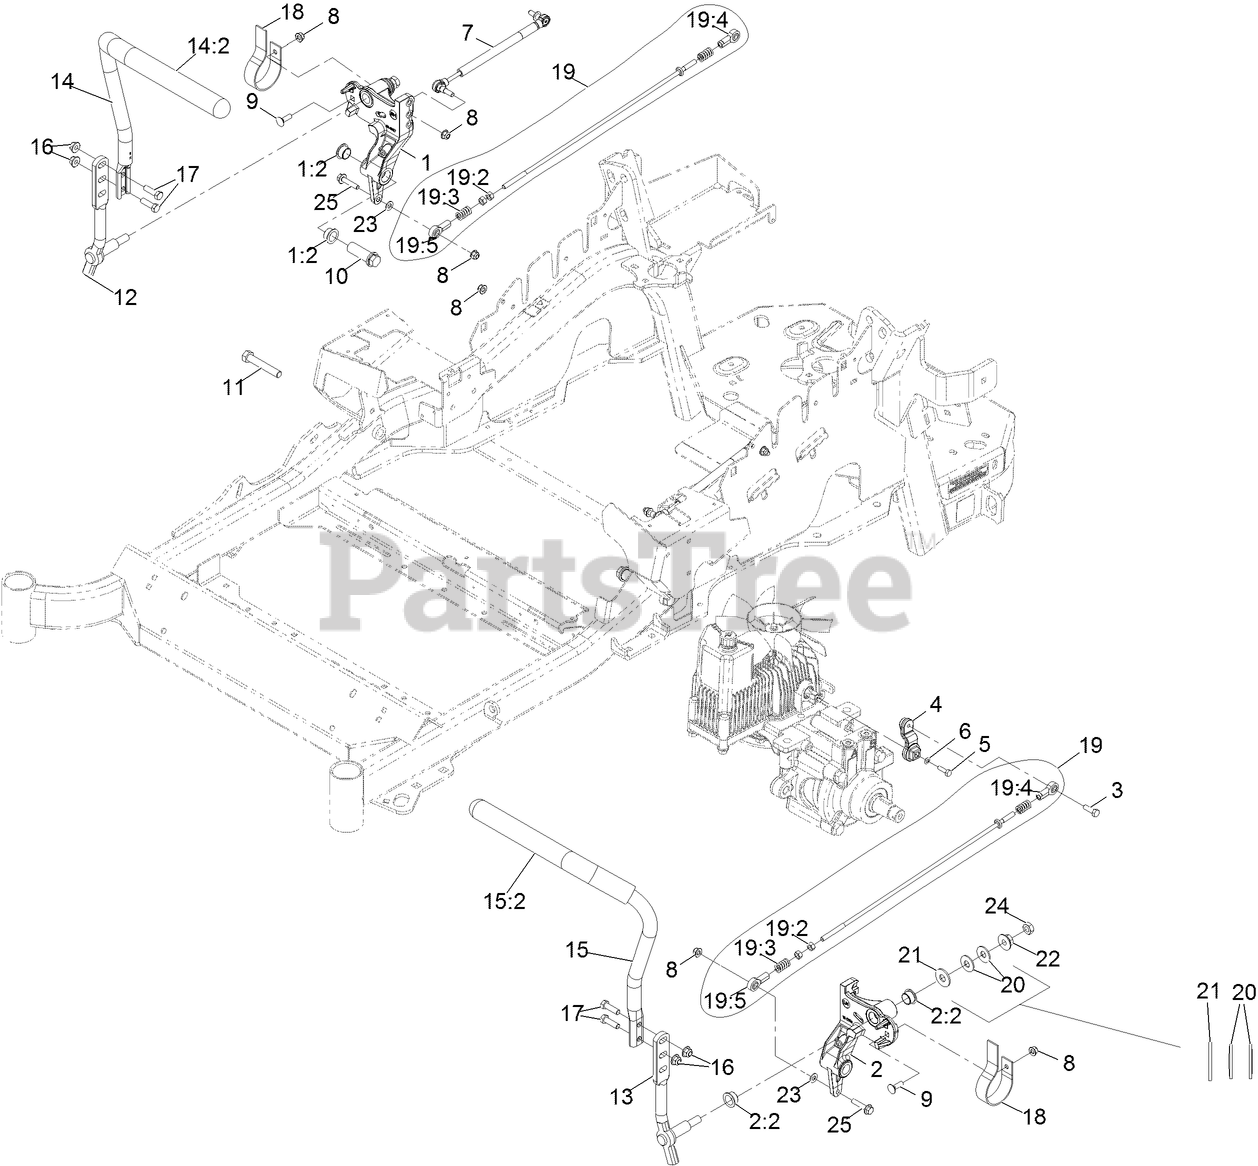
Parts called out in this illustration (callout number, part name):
1	RH MOTION CONTROL AND BUSHING ASM
1:2	BUSHING-FLANGE
2	LH MOTION CONTROL AND BUSHING ASM
2:2	BUSHING-FLANGE
3	SCREW-HH, THREAD LOCKING
4	ARM-CONTROL, PUMP
5	SCREW-HH
6	WASHER-SPRING
7	DAMPER-CONTROL, MOTION
8	NUT-HF, NI
9	BOLT-CARR
10	HUB-THREADED
11	SCREW-HH
12	LEVER-CONTROL MOTION, RH
13	LEVER-CONTROL MOTION, LH
14	HANDLE- RH W/GRIP
14:2	GRIP-CONTROL, LEVER
15	ASM-HANDLE-LH
15:2	GRIP-CONTROL, LEVER
16	NUT-HF, NI
17	SCREW-HH
18	SPRING-LEAF
19	PUMP LINKAGE REAR ASM
19:2	NUT-HEX
19:3	SPRING-COMPRESSION
19:4	BALLJOINT-LH
19:5	BALLJOINT-RH
20	WASHER-SPRING
21	WASHER-FLAT
22	NUT-HF
23	WASHER-PLAIN
24	NUT-JAM
25	SCREW-HHF
